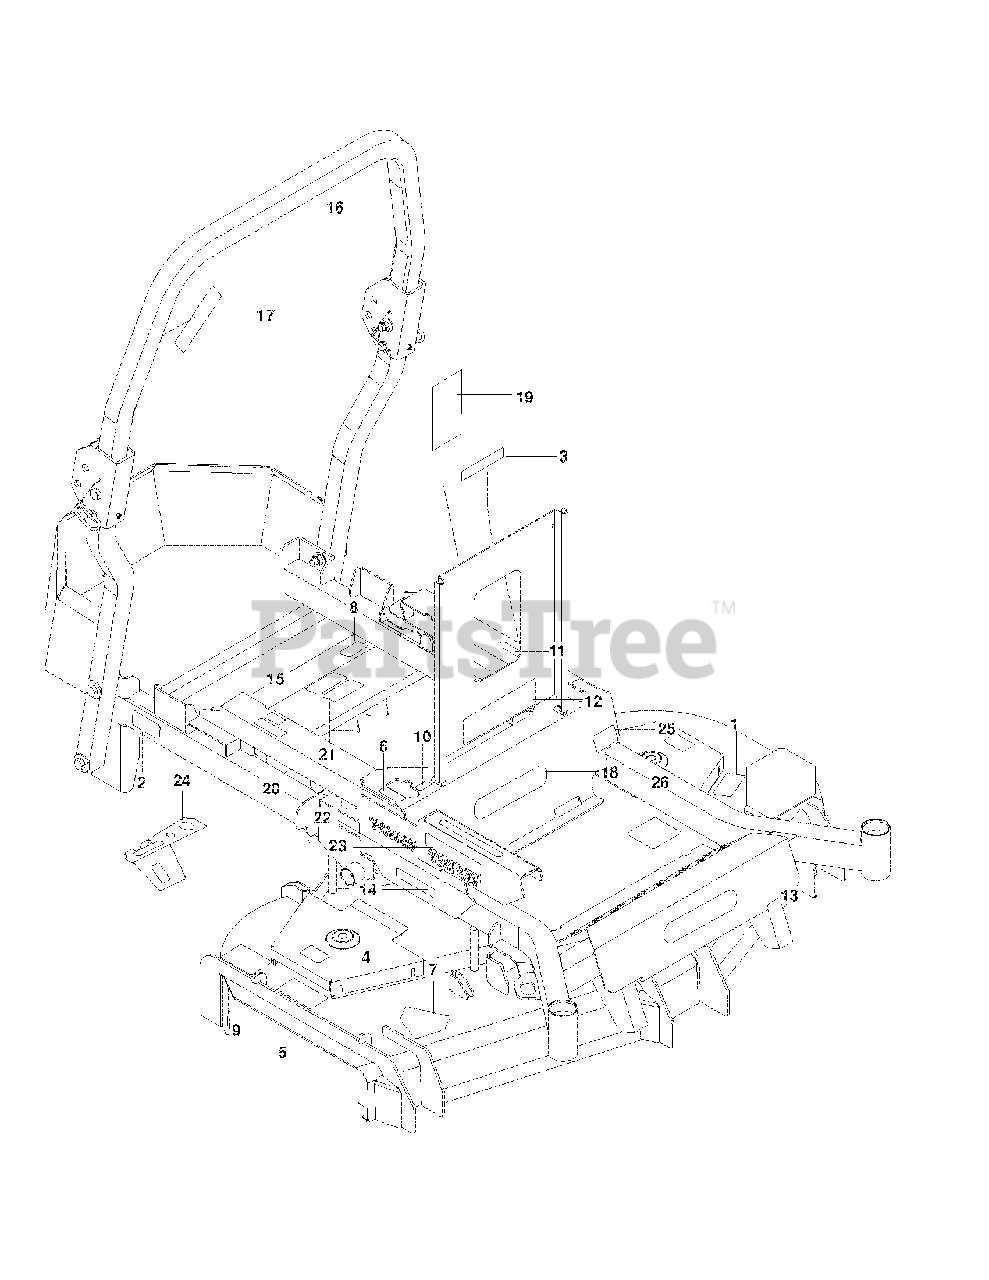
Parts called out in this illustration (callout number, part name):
2	DECAL, BELT DRIVE
5	DECAL, EURO SEVERING
7	DECAL, CPSC
8	DECAL, FUEL
10	DECAL, TRACKING
11	DECAL, PARK BRAKE
12	DECAL, WARNING
14	DECAL, COMMERCIAL
16	DECAL, ROPS
17	DECAL, ROPS, WARNING
18	DECAL, DX200
19	DECAL, SERVICE
20	DECAL, WARNING SPARK ARRESTOR
22	DECAL, HEIGHT
23	DECAL, HEIGHT
25	DECAL, FLAG
26	DECAL, 72" BELT ROUTING
